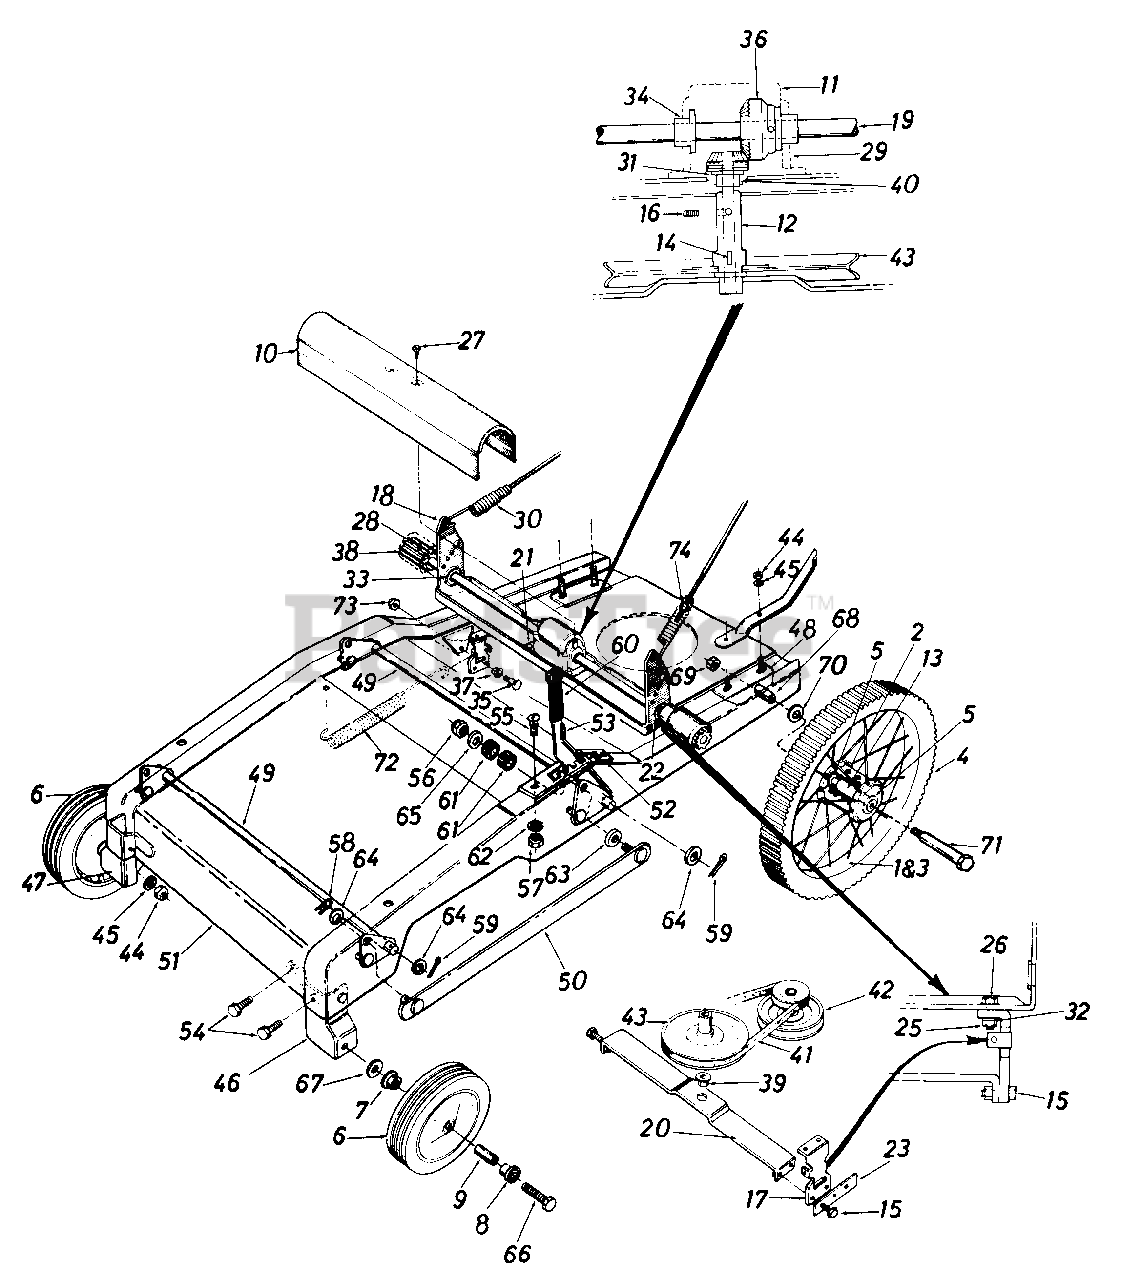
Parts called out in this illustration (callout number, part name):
1	WHEEL ASSY W/TIRE-16 X 1.75 GEM
2	CAP-PLASTIC
3	WHEEL-16 IN
4	TIRE-SEMI PNEU-16 X 1.75 GEAR TR
5	BEARING-BALL
6	WHEEL ASSY W/TIRE-8 X 1.75 TL
7	BEARING-FLANGE
8	BEARING-BALL
10	COVER-TOP DR FRAME ASSY
11	COVER-GEAR BOX
12	PINION ASSY
13	SPACER-WHEEL
14	KEY-WOODRUFF #2-3/32X1/2 DIA-HDN
15	SCREW-HEX SEMS 5/16-18 X 1.00
16	SCREW-SET 5/16-18 X .25 CUP
17	PLATE-BOT DR FRAME
18	FRAME ASSY-TOP DR
19	SHAFT-DRIVE
20	FRAME ASSY-BOT DR
21	SCREW-HEX WASH HD
23	STOP-DR FRAME
25	NUT-HEX 5/16-18
26	SCREW-HEX SEMS 5/16-18 X .75
27	SCREW-HEX WASH HD AB-TAPP #8 X .38
29	KIT-GEAR BOX ASSY
30	SPRING-EXTENSION
32	WASHER-LOCK-5/16
33	BEARING-BALL
34	BEARING-FLANGE
35	SCREW-SHLD .437 DIA X .350
36	GEAR-BEVEL-.62 ID 28T
37	SLIDE-PIVOT
38	PINION-DRIVE
39	BEARING-HEX FLANGE .503 ID
40	BEARING-FLANGE .503 ID
41	BELT-3V-28
42	PULLEY-ENGINE-TWO STEP
44	NUT-HEX CENTER L-3/8-16
45	WASHER-LOCK-3/8
46	BRACKET ASSY-WHL-LH
47	BRACKET ASSY-WHL-RH
48	BRACKET-WHL-RR-LH
49	SHAFT-LIFT BRKT
50	LINK ASSY
52	BRACKET ASSY-SUPPORT
53	HANDLE-LIFT
54	SCREW-HEX SEMS 5/16-18 X .75
55	BOLT-CARRIAGE 5/16-18 X .62
56	NUT-HEX INS L-3/8-24
57	NUT-HEX 5/16-18
58	PIN-INTERN COT-5/16 DIA
59	PIN-COTTER-1/8 DIA X 1.00
60	GRIP-FL BAR-END
61	WASHER-RUBBER
62	WASHER-LOCK-5/16
63	WASHER-FL-.406ID 1.25OD X.157/.172
64	WASHER-FL .510 X .995 X .060
65	WASHER-FL-.385 ID X .87 OD X .06
66	SCREW-HEX 3/8-16 X 2.00
67	WASHER-BELL .400 ID X .88 X .060
68	SPACER-WHEEL AXLE
69	NUT-HEX TOP LOCK-3/8-16
70	WASHER-FL-.531 ID X .93 OD X .090
71	SCREW-SHLD .498 DIA X 4.755
72	SPRING-EXTENSION
73	NUT-HEX INS L-5/16-18
74	NUT-INS LOCK 1/4-20
